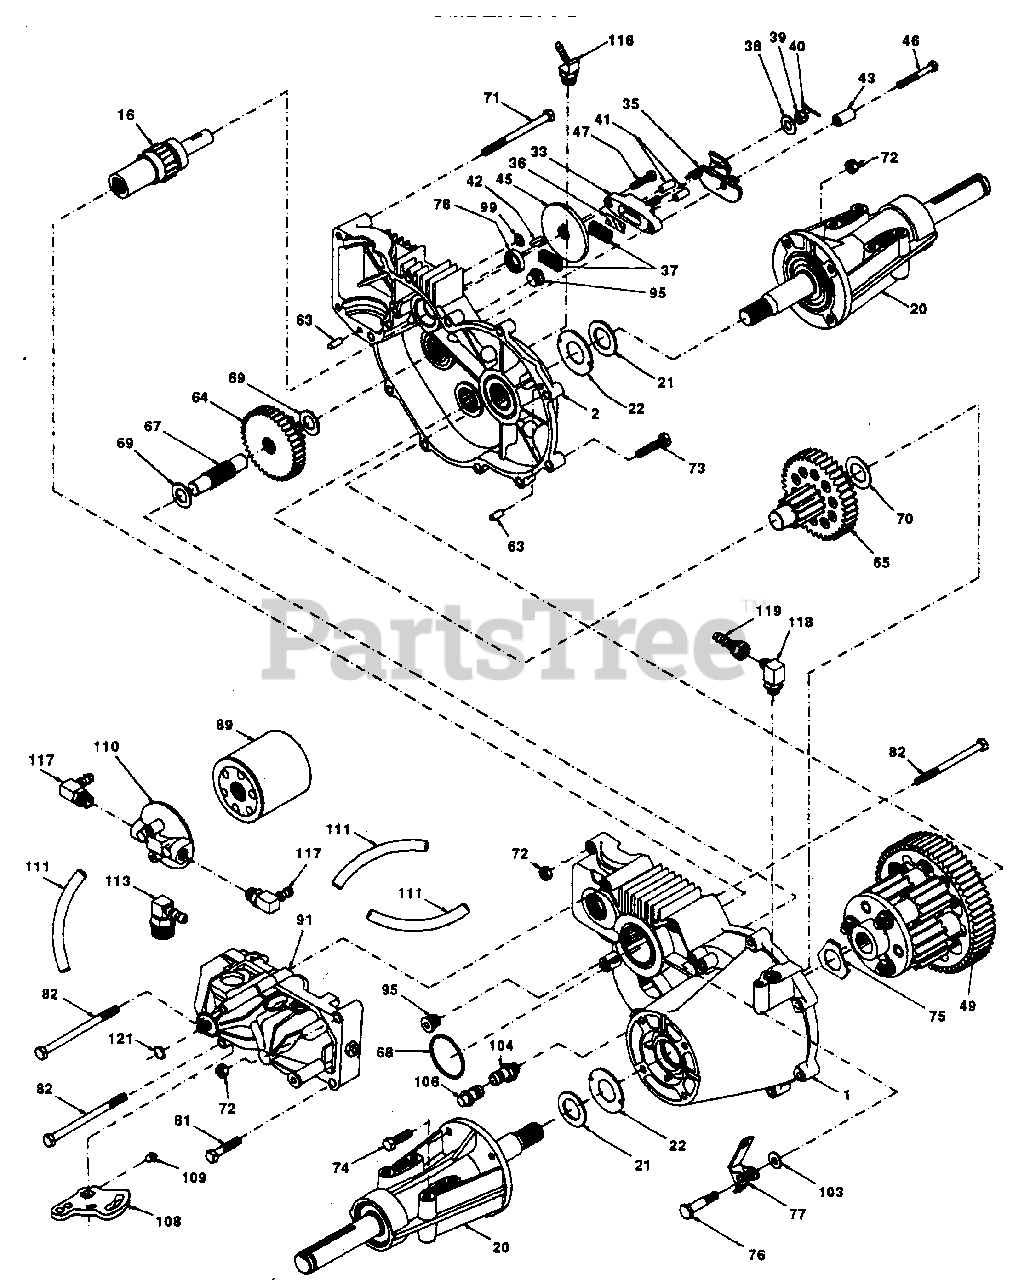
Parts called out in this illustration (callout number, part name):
1	Assembly, Lh Housing (AYP part number)
2	Assembly, Rh Housing (AYP part number)
16	Brake Shaft Assembly (AYP part number)
20	Axle Mounting Horn Ass'y (AYP part number)
21	Washer, 1.0x1.63x.08 (AYP part number)
22	Washer, 1.0x2.06x.09 (AYP part number)
33	Brake Yoke Assembly (AYP part number)
35	Brake Arm (AYP part number)
36	Puck Plate (AYP part number)
37	Brake Puck (AYP part number)
38	Washer, 7/8odx7/16x.060 (AYP part number)
39	Castle Nut, 5/16-24 (AYP part number)
40	Cotter Pin (AYP part number)
41	Brake Actuating Pin (AYP part number)
42	Hi Pro Key (AYP part number)
43	Spacer (AYP part number)
45	Brake Disc (AYP part number)
46	Bolt, 1/4-20 X 1-1/2 (AYP part number)
47	Bolt, 1/4-20 X 1 (AYP part number)
49	Differential Assembly (AYP part number)
63	Dowel Pin (AYP part number)
64	14t-38t Reduction Gear (AYP part number)
65	Final Drive Pinion Ass'y (AYP part number)
67	Jack Shaft (AYP part number)
68	O Ring (AYP part number)
69	Washer,5/8 X 1-5/32 (AYP part number)
70	Washer,7/8 X 1-1/2 (AYP part number)
71	Bolt, Hex 5/16-18 X 3.5 (AYP part number)
72	Hex Lock Nut, 5/16-18 (AYP part number)
73	Bolt, Hex 5/16-18 X 1-1/2 (AYP part number)
74	Hex Cap Screw, 5/16-18 X 1 (AYP part number)
75	Washer, Differential (AYP part number)
76	Shoulder Bolt (AYP part number)
77	Freewheel Actuating Arm (AYP part number)
78	Oil Seal, .625 X 1.0 X .25 (AYP part number)
81	Bolt, Hex 5/16-18 X 1-3/4 (AYP part number)
82	Bolt, 5/16-18 X 4-1/2 (AYP part number)
89	Spin On Filter (AYP part number)
91	Bdu-10l-118 (AYP part number)
95	Straight Thread Plug (AYP part number)
99	Washer, 11/32 X 9/16 (AYP part number)
103	Washer (AYP part number)
104	Cap-Vent Assembly (AYP part number)
106	Fitting-O Ring Assembly (AYP part number)
108	Control Arm (AYP part number)
109	Set Screw (AYP part number)
110	Filter Head (AYP part number)
111	Hose, 5/16 X 12" Long (AYP part number)
113	90 degree 7/8 Sae Fitting (AYP part number)
116	45 degree 9/16 Sae Fitting (AYP part number)
117	90 degree 9/16 Sae Fitting (AYP part number)
118	90 degree Sae #6 Flare Male Fitting (AYP part number)
119	90 degree Sae #6 Flare Female Fitting (AYP part number)
121	Wire Retaining Ring (AYP part number)
